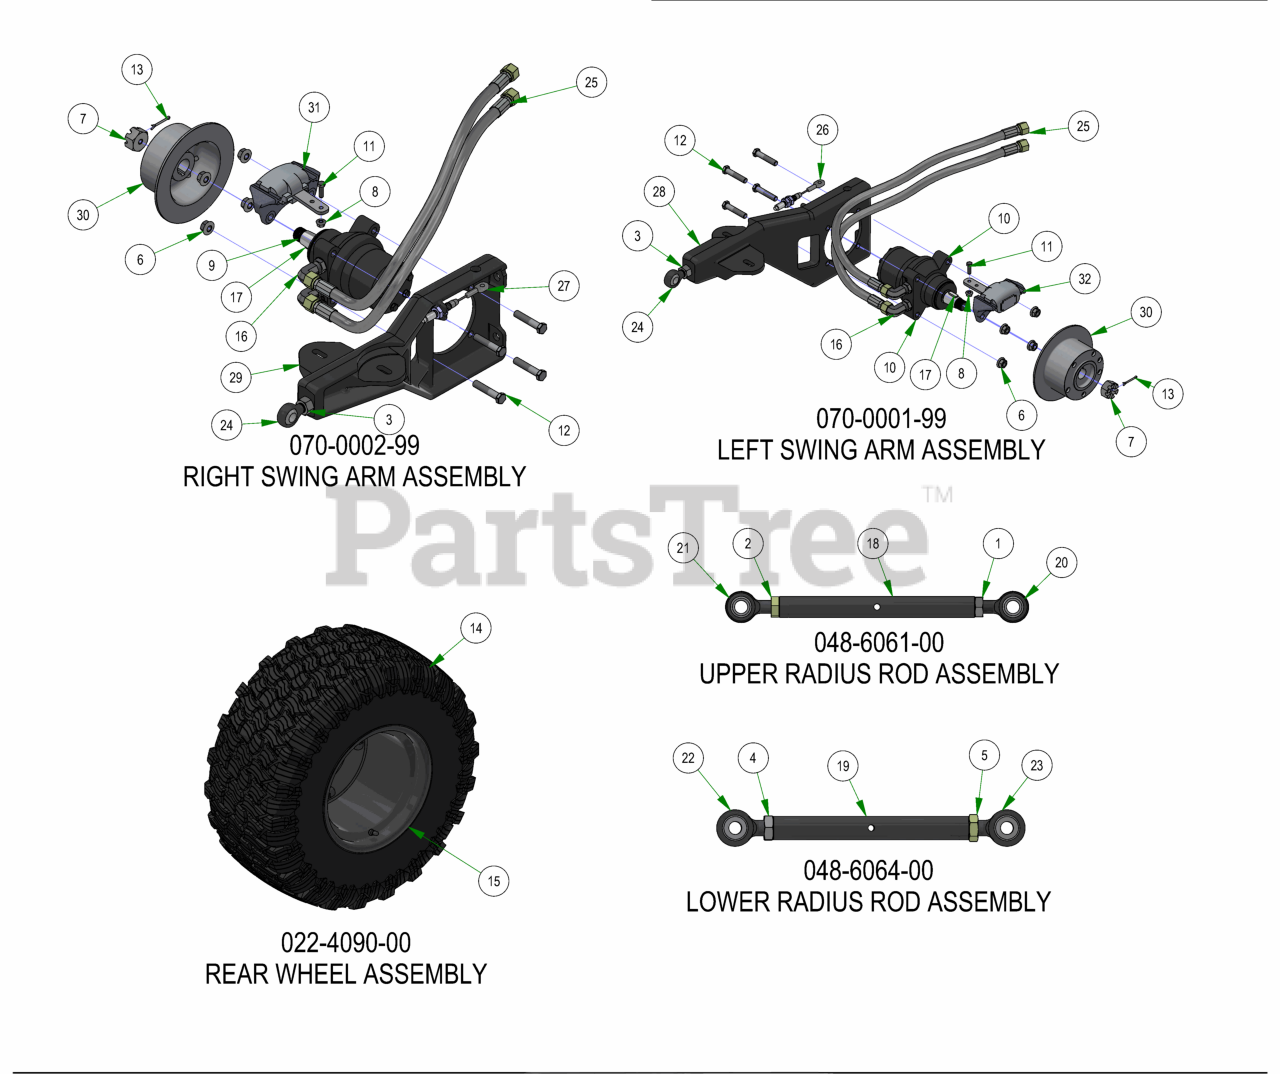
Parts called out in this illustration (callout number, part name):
1	5/8-11 HEX JAM NUT ZINC
2	NUT, 5/8-18LH
3	3/4"-16 Fine Full Nut
4	3/4-16 HEX JAM NUT ZINC
5	3/4-16 LH HEX JAM NUT ZINC
6	1/2-13 Gr 8 Centerlock Flange Nut
7	1" Castle Nut for HydroGear Wheel Motor
8	5/16-18 NYLON INSERT FLANGE LOCKNUT ZINC
9	18cc Parker Wheel Motor- Right
10	18cc Parker Wheel Motor- Left
11	5/16-18 X 1 HEX CAP SCREW (GR.5) ZINC
12	1/2-13 x 2.75 Gr. 8 Hex Head Bolt
13	1/8 X 1-1/2 COTTER PIN ZINC
14	2019 26x12-12 Reaper Turf Tire
15	2019 10.5" Wheel
16	2019 Rouge/Renegade Wheel Motor 90* Fitting #6801-10L
17	Woodruff Key
18	2019 Suspension Link Body
19	Rear Radius Rod, 3/4 Body
20	2019 RH 5/8" Heim
21	2019 LH 5/8" Heim
22	3/4-16 x 5/8 RH Heim
23	3/4-16 x 5/8 LH Heim
24	3/4-16 RH Male Rod End
25	2019 Renegade Hydro Hose
26	2019 Short Brake Cable-Suspension Models
27	2019 Long Brake Cable-Renegade, Rogue
28	2019 Left Trailing Arm
29	2019 Right Trailing Arm
30	Brake Disk
31	XP/AOS Right Brake Caliper
32	XP/AOS Left Brake Caliper
